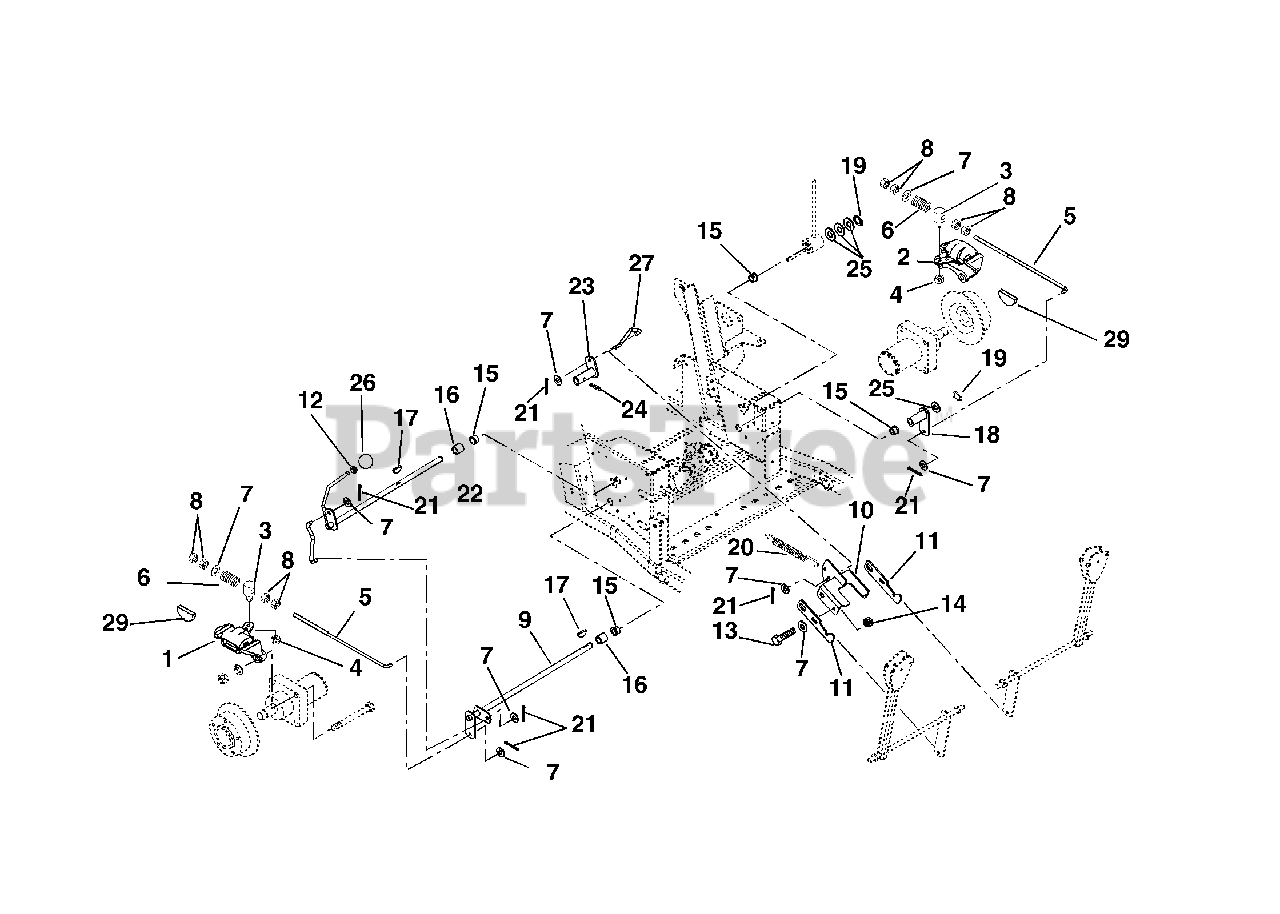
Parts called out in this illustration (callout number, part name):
1	Caliper, Park Brake (CW) Right Hand
2	Caliper, Park Brake (CCW) Left Hand
3	Pivot-Brake Rod
4	Nut-Locking-Center .31-18
5	Rod-Brake 12 inch
6	Spring-Compression .143 x .710 x 2.00
7	Washer-Flat-Steel .406 x .812 x .065
8	Nut-Hex .38-16
9	Shaft-Brake Cross
10	Interlock-Fixed
11	Interlock-Adjustable
12	Nut-Hex-Jam .375 -16
13	Bolt-Hex .38-16 x 1.00 Grade 5
14	Nut-Locking-Center .38-16
15	Bushing-Flange .630 x 1.000 x .625
16	Spacer .630 x .878 x 1.000
17	Key-Woodruff .19 x .75 Hard #9
18	Arm-Brake Left-Hand
19	Ring-Retaining-External .625 x .050
20	Spring-Tension .105 x .85 x 5.00
21	Pin-Cotter External .09 x .75
22	Shaft-Brake Actuating
23	Actuator
24	Pin-Roll .125 x 1.00
25	Washer-Flat-Steel .627 x .990 x .032
26	Knob-Steering Lock
27	Rod-Brake Actuating
28	Pin-Cotter-External .09 x .75 r
29	Pad, Disk Brake
